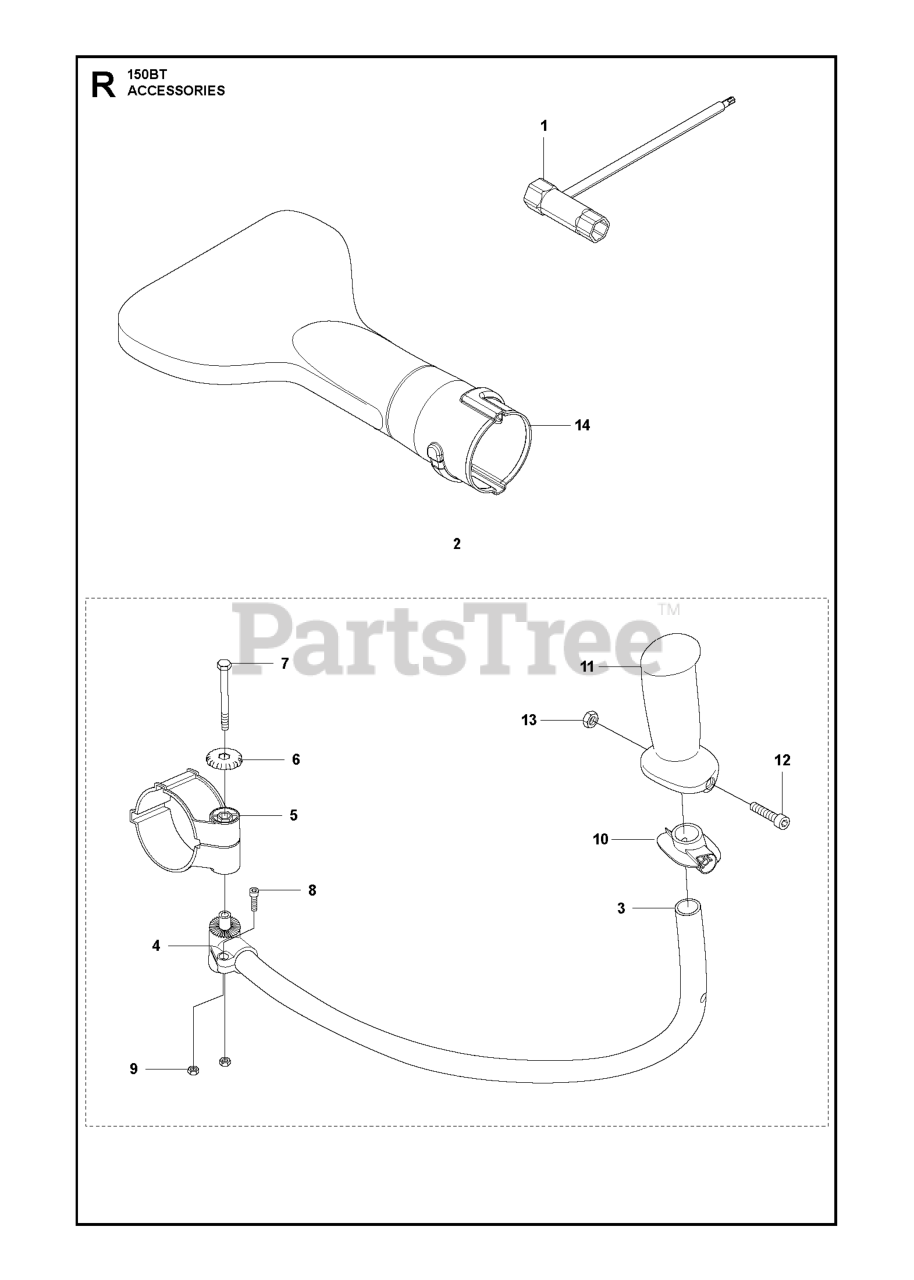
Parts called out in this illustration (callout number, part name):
2	HANDLEBAR ASSY
5	HOLDER TH
8	SCREW MC6S 5X10
14	FLAT NOZZLE
